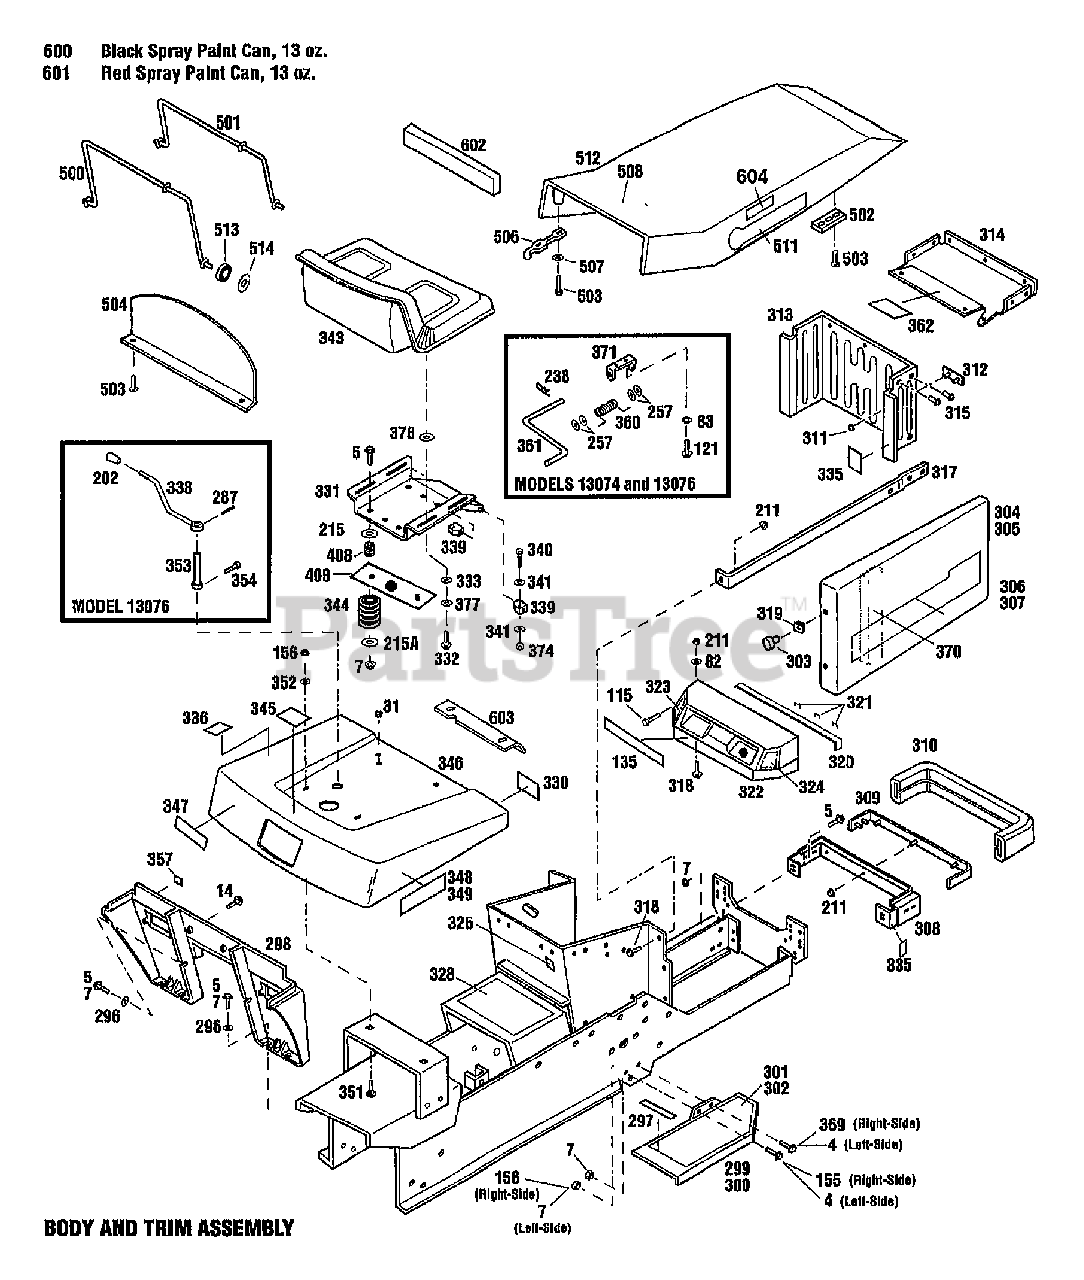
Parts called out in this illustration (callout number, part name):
5	SCR-HFLK 3/8-16X1.00 ZP
7	NUT-HFLK 3/8-16 ZP
14	SCR-HFLK 5/16-18X.75 ZP
31	GROMMET
82	WASHER-FLAT 1/4 SAE
83	WASHER-LK .25 ZP
115	SCR-PHP M6-32X.38 ZP
121	SCR-HH 1/4-20X.5 GR5 YEL
135	LENSE
155	SCR-TRUSS HD 5/16-18X.62
156	NUT-HFLK 5/16-18 ZP
202	KNOB-SHIFT LEVER
211	NUT-HF/LK 1/4-20 ZP
215	WASHER-FLAT 1.25X.406X.179
238	PIN-COTTER .09X.75 ZP
257	WASHER-FLAT 5/16 SAE
287	PIN-ROLL .188X1.0
296	WASHER-.986X.437X.083 ZP
297	CUSHION
298	SUPT-RUNNING BOARD
299	FOOTREST-LH
300	FOOTREST-RH
301	PAD-FOOTREST LH
302	PAD-FOOTREST RH
305	COVER-RH
306	DECAL-SIDE COVER LH
307	DECAL-SIDE COVER RH
308	ASSM-GRILLE SUPT
309	ASSM-BUMPER STRAP
310	BUMPER-EXTRUSION
311	NUT-PUSH
312	PLATE-LOGO
313	GRILLE-TRACTOR
314	CAP-GRILL
315	RIVET-POP
317	SUPPORT
318	SCR-HH 1/4-20X.625
319	NUT-SPEED #10
320	PAD-HOOD
321	WIRE STAPLE
322	PANEL-INSTRUMENTS
323	DECAL-CHOKE
324	DECAL-THROTTLE
325	DECAL-IGNITION
328	DECAL-OPERATING INST
330	DECAL-AMERICAN LEGEND-LRG
331	ASSM-SEAT SUPPORT
332	SCR-SHLDR 3/8-16X.25 G5ZP
333	WASHER-1.375X.523X.059
335	PAD-BATTERY
336	DECAL-TWO SPEED
338	LEVER-SHIFT
339	BLOCK-PIVOT
340	SCR-HH 5/16-18X1.5 G5 ZP
341	WASHER-1.5X.343X.104
343	SEAT (TRACTOR)
344	SPRING-COMPRESSION
345	DECAL-FUEL
346	FENDER-REAR
347	DECAL-LOGO FENDER
348	DECAL-FENDER LH
349	DECAL-FENDER RH
351	BOLT-CARR 5/16-18X.63 ZP
352	WASHER-1.25X.343X.059
353	SHAFT-SHIFT LEVER
354	SCR-SQHD 1/4-20X1/2 GR5
357	BUTTON-RUBBER
360	SPRING-TORSION
361	BRACKET-SEAT ADJ
362	DECAL-HOT SURFACE
369	SCR-HH 3/8-16X.75 G5 ZP
370	BLOCK-SEALING
371	BRKT-SEAT ADJUST
374	NUT-TOP/LK 5/16-18 ZP
377	WASHER-BOW .74X.52X.01
378	WASHER-FLAT
408	SPRING-COMPRESSION
409	CHANNEL-SEAT SWITCH
500	LINK-HINGE
501	LINK-HINGE
502	RETAINER-HINGE LINK
503	SCR-SEMS MACH
504	BAFFLE-HOOD
506	LATCH-RUBBER
507	WASHER-.88X.2X.059
508	DECAL-SERVICE INST
511	DECAL-LOGO
512	ASSM-HOOD
513	GROMMET
514	RETAINER
600	PAINT-BLACK SPRAY
601	PAINT-RED SPRAYCAN POWDER
602	BLOCK-SEALING
603	BRKT-DOUBLER (USED ON LATER PROD UNITS ONLY)
604	DECAL-LOGO
